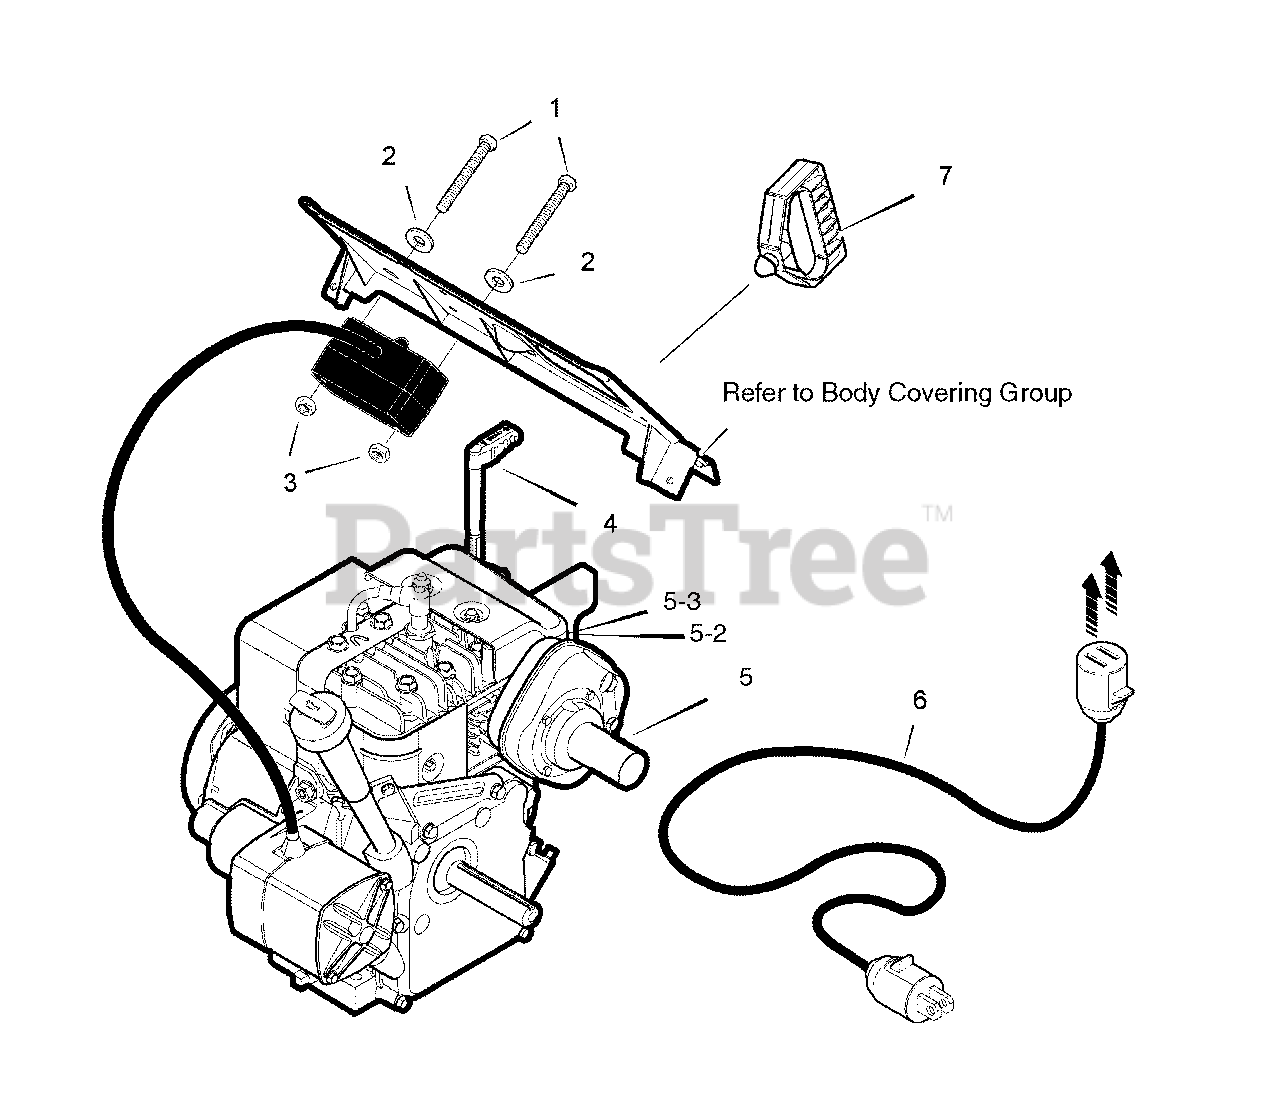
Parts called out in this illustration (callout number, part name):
1	SCREW, No. 8-32 x 3.00
2	WASHER, FLAT No. 8
3	NUT, Keps No. 8
4	* LEVER, Choke
5	* KIT, Muffler Assembly
5-2	* GASKET, Muffler
5-3	* BOLT, Muffler
6	CORD, Electric 110V 10 Feet
6	CORD, Electric 220V 10 Feet
7	GRIP, Starter Rope
